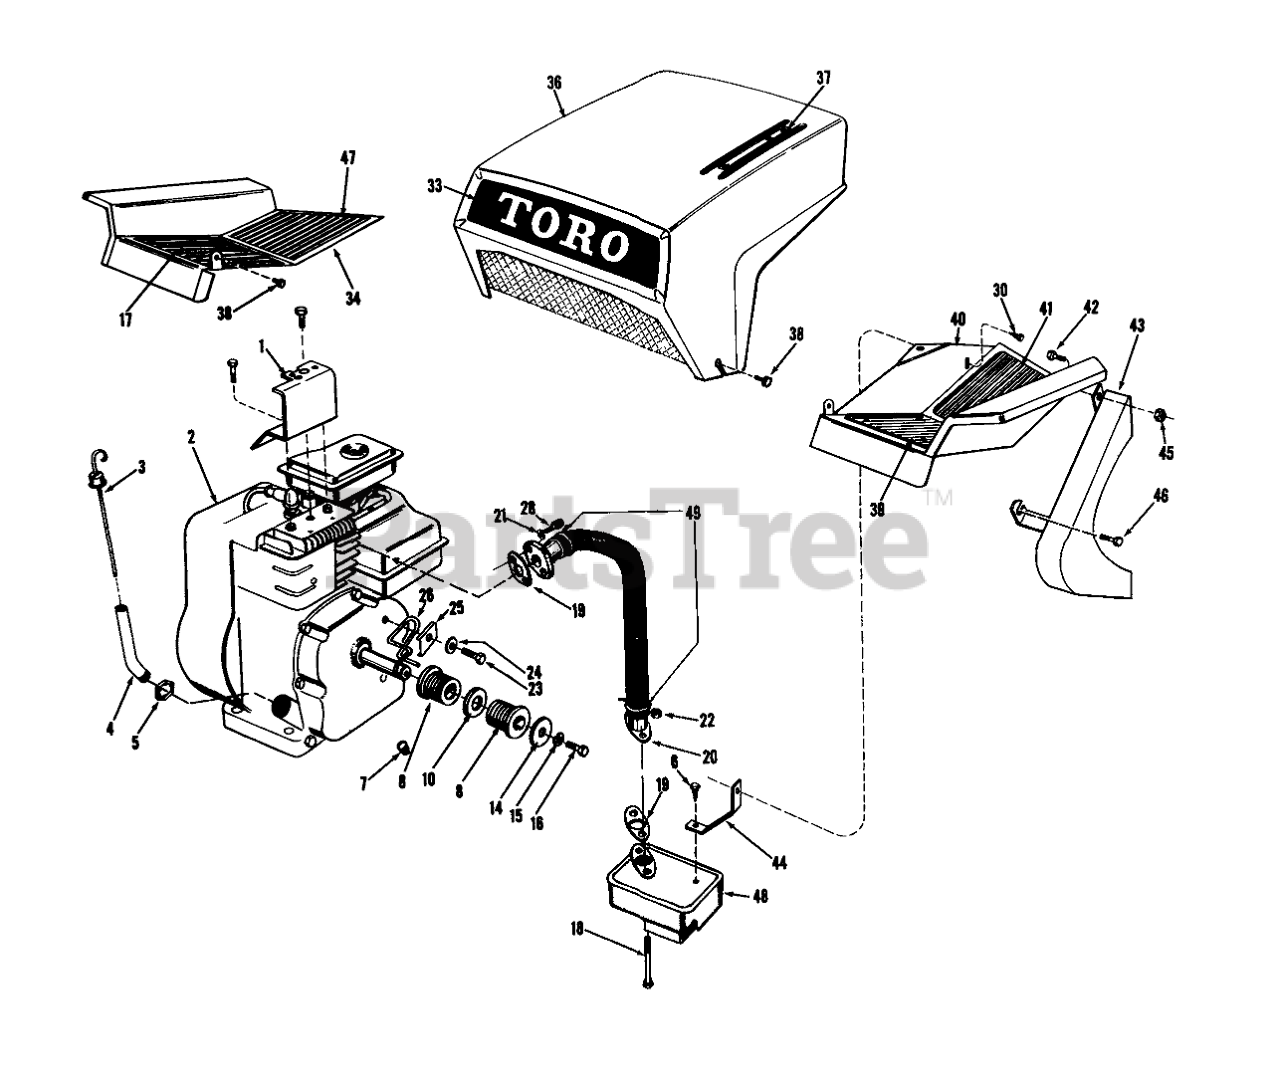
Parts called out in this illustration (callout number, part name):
2	Engine
6	SCREW-HWHTF
7	PLUG-PIPE, SQH
10	WASHER-THRUST
15	WASHER-LOCK
16	SCREW-HH
18	Capscrew
21	WASHER-LOCK
22	NUT-KEPS
24	WASHER-FLAT
26	Guide
28	SCREW-HSH
30	10-16 X 3/8 THDG SCREW
46	SCREW-HH
48	Muffler
